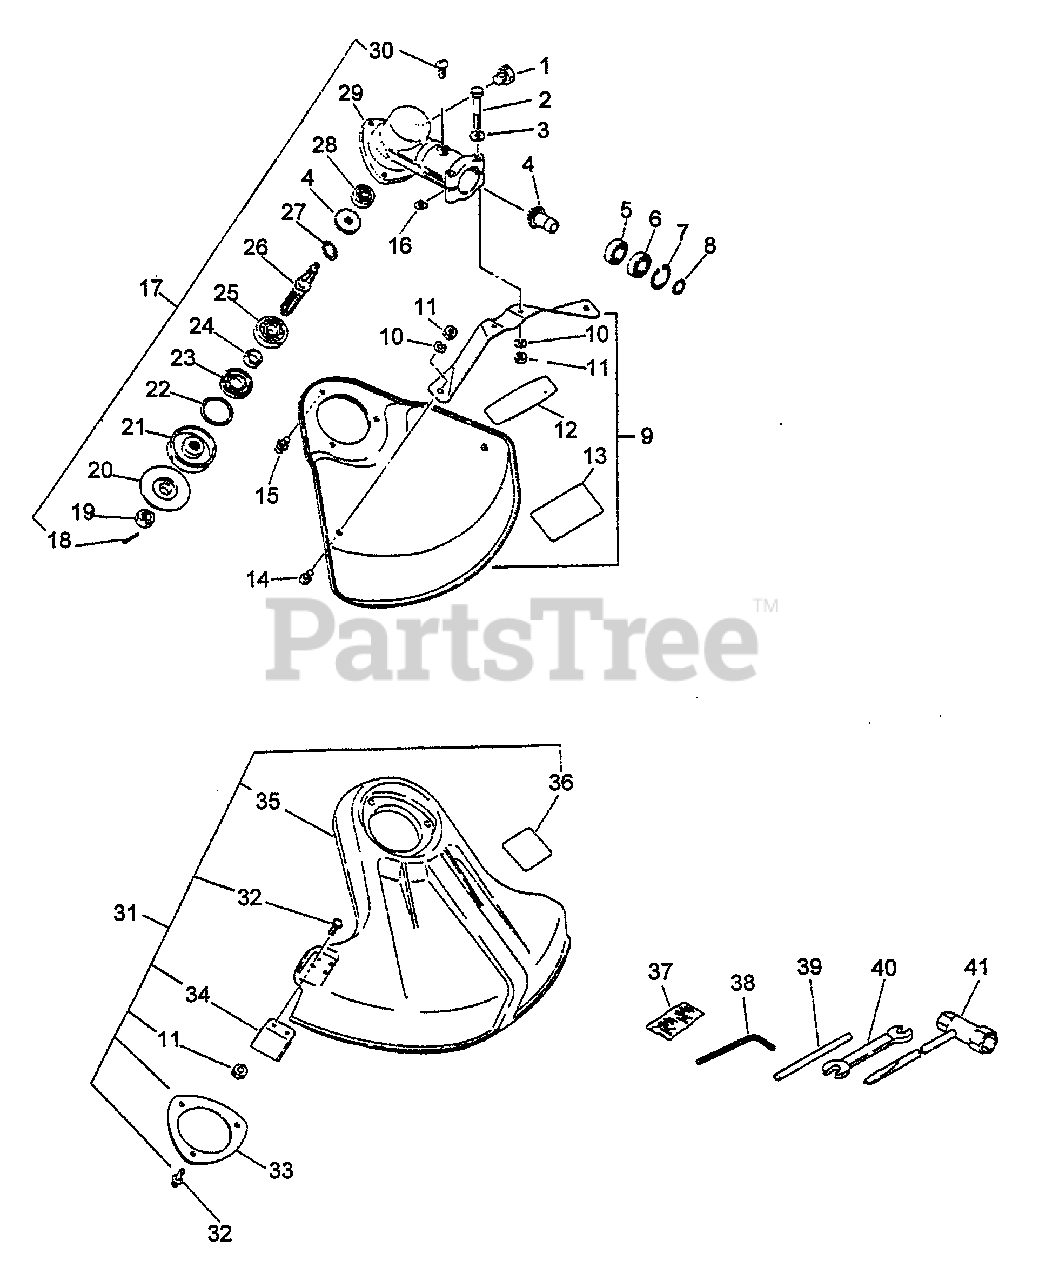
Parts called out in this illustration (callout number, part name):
1	BOLT - 8X8
2	BOLT - 5X40
3	WASHER - 5
4	GEAR SET - BEVEL
5	BEARING, BALL - 6001C3
6	BEARING, BALL - 6001
7	RING, RETAINING - 28
8	RING, RETAINING - 12
9	DEBRIS SHIELD KIT - METAL
10	LOCKWASHER - 5
12	LABEL - ECHO
13	LABEL - DANGER
14	SCREW - 5X8
15	SCREW - 5X10
17	GEAR CASE ASSY
18	PIN, SPLIT - 2X22
19	NUT - 10 -- LEFT HAND
20	ADAPTOR, BLADE - LOWER
21	ADAPTOR, BLADE - UPPER
22	RING, RETAINING - 32
23	SEAL, OIL
25	BEARING, BALL - 6201
26	GEAR - SHAFT
27	RING, RETAINING - 12
28	BEARING, BALL - 6000
29	CASE, GEAR
30	SCREW - 5X10
31	DEBRIS SHIELD KIT
32	SCREW - 5X16
33	PLATE, SHIELD
34	KNIFE, TRIMMER LINE
35	SHIELD, DEBRIS - PLASTIC
36	LABEL - CAUTION
37	PIN, SPLIT - 2X22
38	HEX KEY - 4mm
39	LOCKING TOOL
40	SPANNER - 8X10mm
41	T-WRENCH - 17X19mm
